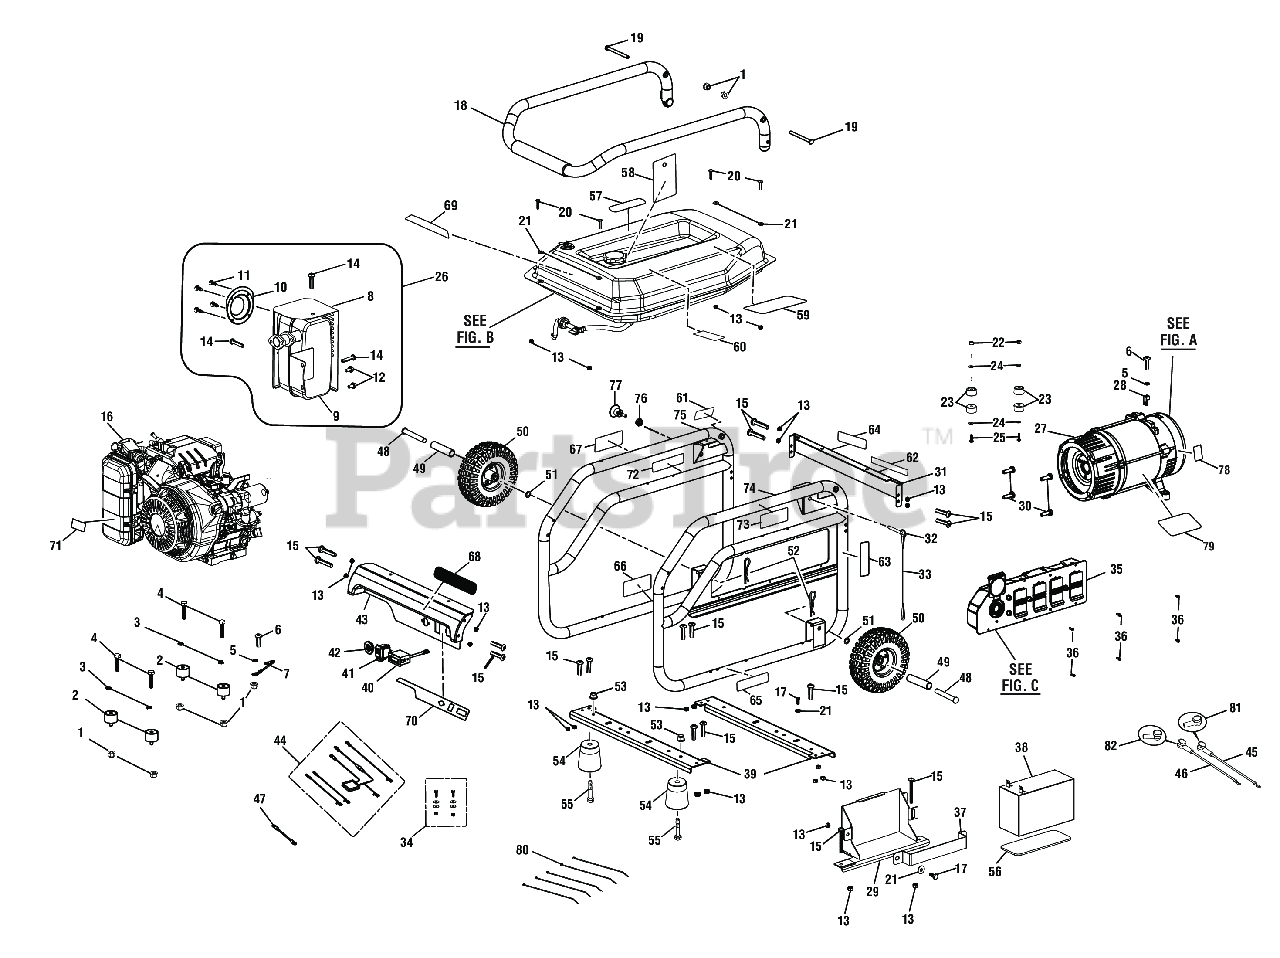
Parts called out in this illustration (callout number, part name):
1	Flange Lock Nut (M8 x 1.25 mm)
2	Isolator Generation 7
3	Lock Washer (OD14.8 x ID8.5 x 1t)
4	Bolt (M8 x 1.25 in., Hex Hd.)
5	Star Washer (M8)
6	Bolt (M8 x 15 mm, Hex Hd.)
7	Assembly, ground wire
8	Heat Shield
9	Muffler w/Brackets
10	Spark Arrester Screen
11	Screw (8-32 x 3/8 in., Pan Hd.)
12	Bolt (5/16-24 x 0.6 in., Hex Hd.)
13	Lock Nut (M6 x 1 mm)
14	Bolt (M6 x 9 mm, Hex Flange Hd.)
15	Screw (M6 x 50 mm, T30 Torx Pan Hd. )
16	Engine (Subaru EA190)
17	Screw (M6 x 16 mm, Hex Hd.)
18	Handle Assembly
19	Handle Pivot Bolt (M8 x 98 mm, Flat Hd.)
20	Bolt (M6 x 25 mm, T30 Torx Hd.)
21	Washer (OD17 x ID6.4 x 1.6t)
22	Lock Nut (M4)
23	Rubber Bumper
24	Washer (ID4.3 x OD10 x 0.9t)
25	Screw (M4 x 12 mm, Button Hd.)
26	Muffler Assembly
27	Generator Head (See Figure A)
28	Ground Lug (1/4-20)
29	Battery Box Gasket
30	Bolt, Wiz (3/8-18 x 1-1/4 in.)
31	Fuel Tank Support (Back)
32	Release Pin (5/16 x 2 in.)
33	Lanyard (3/16 in.)
34	Fastener Kit (Wiring)
35	Control Panel Assembly (See Figure C)
36	Screw (6-20 x 3/8 in., Phillips Pan Hd.)
37	Battery Hold Down Bracket Assembly
38	Battery Bracket
39	Frame Crossbar
40	Multifunctional display
41	Start Switch w/Lock
42	Fuel Valve Bezel
43	Fuel Tank Support (Front)
44	Wiring Harness
45	Battery Cable (Black 390 mm)
46	Battery Cable (Red)
47	Bonding Wire
48	Axle Bolt (M10 x 125 mm, Hex Hd.)
50	Wheel (10 in. x 3 in.)
51	Washer (OD19.75 x ID10.5 x 1t)
52	Hitch Pin (M3)
53	Lock Nut (M8 x 1.25)
54	Foot Assembly
55	Bolt (M8 x 1.25 in., Flange Hex Hd.)
57	CPSC Label (Eng/Sp)
58	Warning Hang Tag (Eng/Sp)
59	Icon Warning Label
60	No E85 Label
61	Handle Release Label
62	Ground Warning Label
63	Lock and Pin Label
64	Inquiries Label.
65	Engine Lubricant Label
66	Combustion Label (English/Spanish)
67	Fire Distance Label (Eng/Sp)
68	Logo Label (Honda)
69	Logo Label (Black Max, Long)
70	Start Label
71	Electric Start Label
72	Hot Surface Label
73	Risk of fire danger label
74	Frame (Right)
75	Frame (Left)
76	Lock Nut (1/2-20, Hex)
77	Handle Lock Assembly
78	Ground Label Icon
79	Data Label
80	Zip Tie, (5-1/2 in., Black)
81	Rubber Battery Cable Boot (Black)
82	Rubber Battery Cable Boot (Red)
